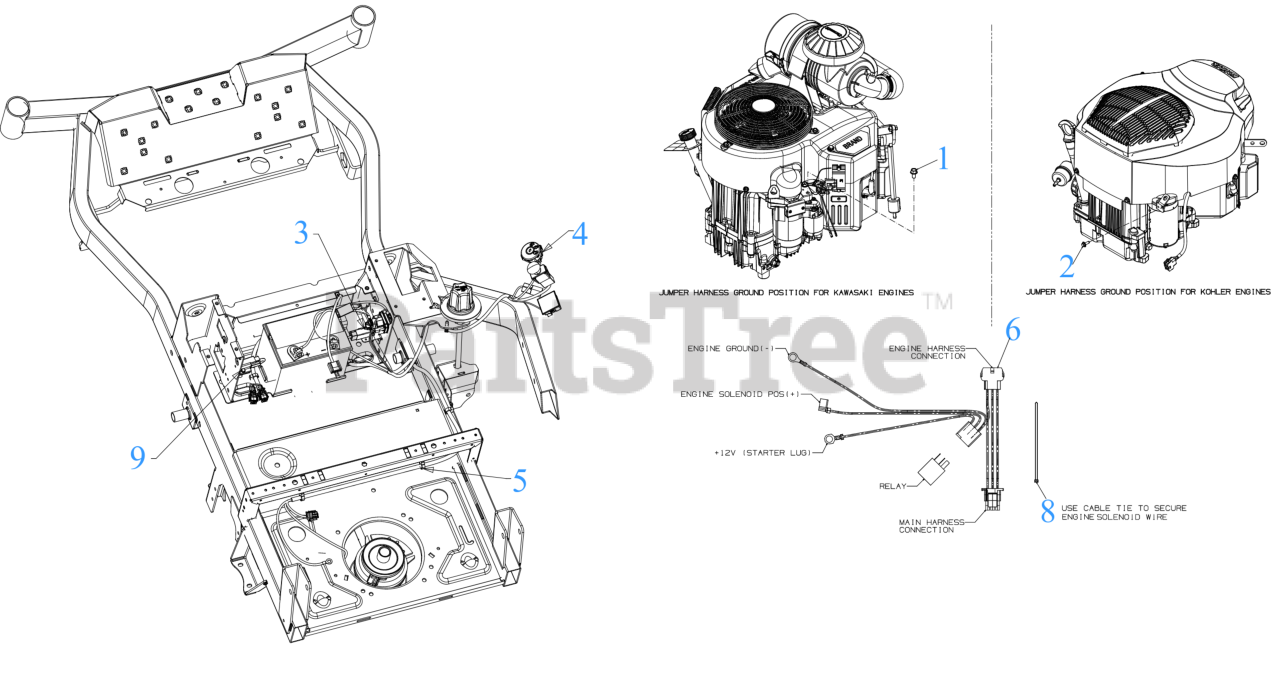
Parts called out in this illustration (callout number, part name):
1	SCREW M8 x 1.25 x 16MM GR8.8
2	SCREW M6-1 x .625
3	INTERLOCK SWITCH (NO/NC)
4	KEY SWITCH (3 POS 6 PIN)
5	MAIN HARNESS
6	JUMPER HARNESS (W/RELAY)
8	CABLE TIE
9	SHOULDER SCREW
